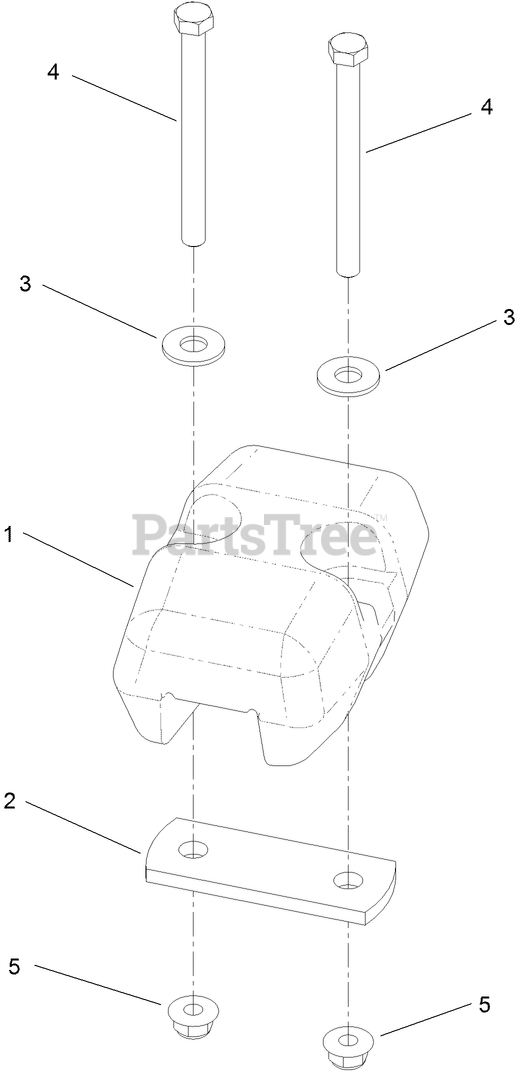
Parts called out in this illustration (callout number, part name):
1	WEIGHT-SUPPORT, CASTER
2	BRACKET, FRONT WEIGHT
3	WASHER-FLAT
4	SCREW-HH
5	NUT-HF, NI
